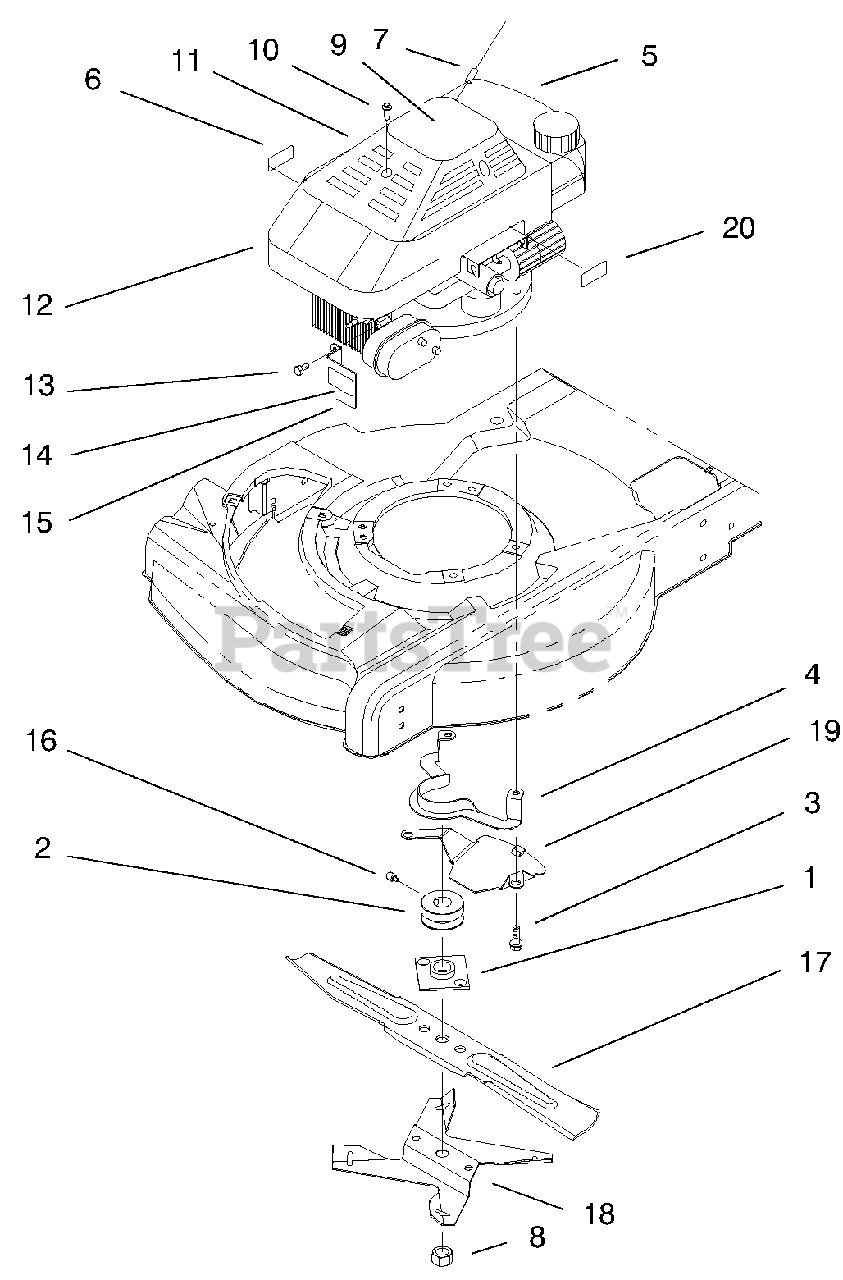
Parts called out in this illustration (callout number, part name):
1	Plate & Collar Assembly
2	Pulley-Engine
3	Screw-Engine
4	Guide-Belt
5	Engine
6	Decal-Oil Instruction
7	Rope-Stop
8	Nut-Blade
9	Decal-Recoil
10	Screw-Recoil Cover
11	Cover-Starter
12	Shroud-Engine
13	Screw-Hex Socket Hd.
14	Decal-Warning
15	Guard-Muffler (Incl. Ref. #14)
16	Screw-Set
17	Blade-21" Whirl
18	Fan-Mulching
19	Shield-Grass
20	Decal-Primer
